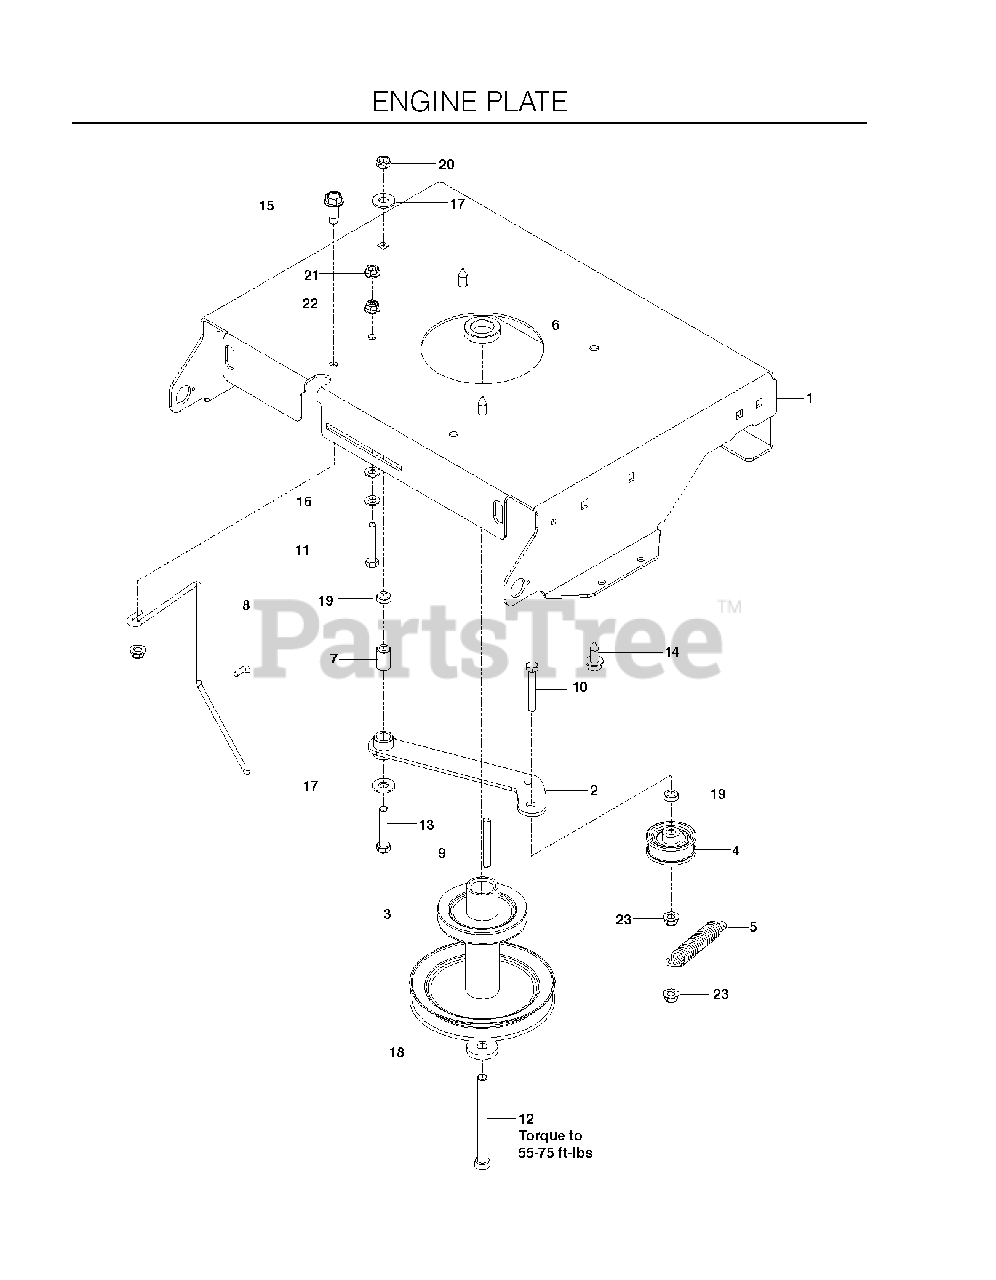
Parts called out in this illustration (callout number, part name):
2	IDLER ARM WLDMNT, BLACK
3	PULLEY IDLER
4	PULLEY, ENGINE 6.5
5	SPRING - 3.50
7	BUSHING
8	KEEPER, BELT ENGINE
9	KEY 1/4 SQ X 2-1/2
10	TAPBOLT, 3/8C X 3
11	HCS 5/16-18X2
12	HCS 7/16-20 X 4 GR5 ZD
13	HCS 3/8C X 2
14	HHFS 3/8-16 X 1.0 THD FORMING
15	BOLT 3/8-16 X 1.0
16	FLAT WASHER 5/16 SAE
17	WASHER 3/8 FLAT
18	WASHER .43X1.38X.25
19	WASHER 3/8 X 3/4 X .187 TK
20	NUT HEX 3/8-16 NYLON, THIN
21	NUT 5/16C WHIZ
22	5/16-18 NYLOC FLANGE NUT
23	NUT 3/8-16 HEX FLG NYLOC ZD
